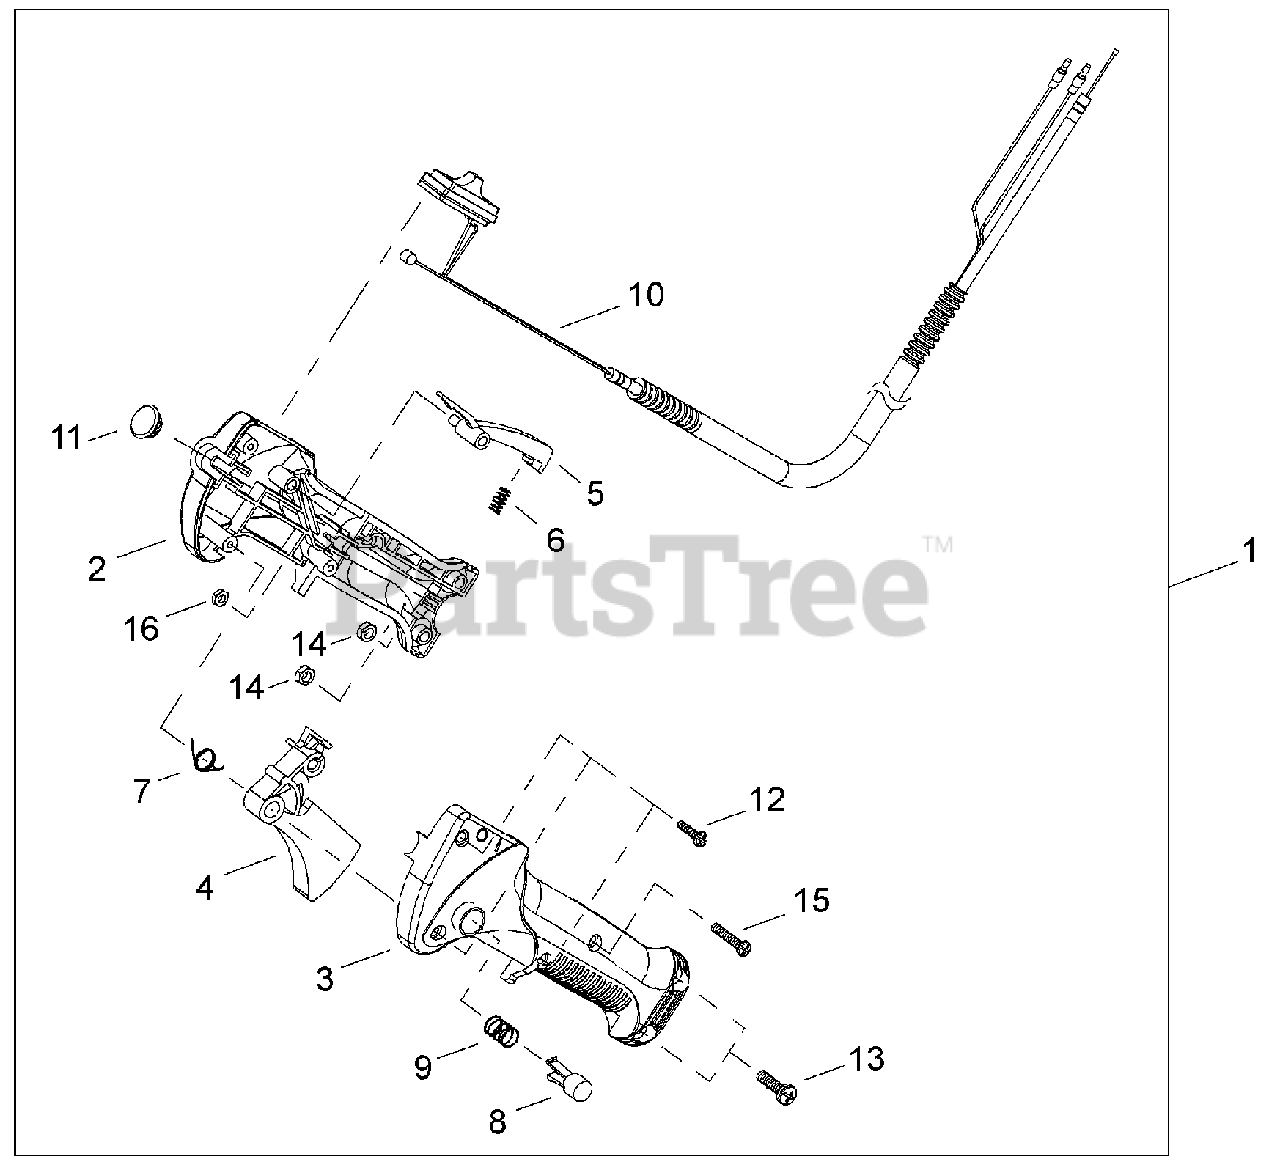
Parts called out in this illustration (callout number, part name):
1	THROTTLE CONTROL ASSY
2	CONTROL HANDLE - RIGHT
3	CONTROL HANDLE - LEFT
4	TRIGGER, THROTTLE
5	LOCKOUT, THROTTLE
6	SPRING, COMPRESSION
7	SPRING, TORSION
8	BUTTON, THROTTLE LOCK
9	SPRING, COMPRESSION
10	CABLE ASSY, CONTROL
11	PLUG, RUBBER
12	SCREW, TAPPING 4×16
13	SCREW M5×20
14	NUT M5
15	SCREW M4×23
16	NUT M4
